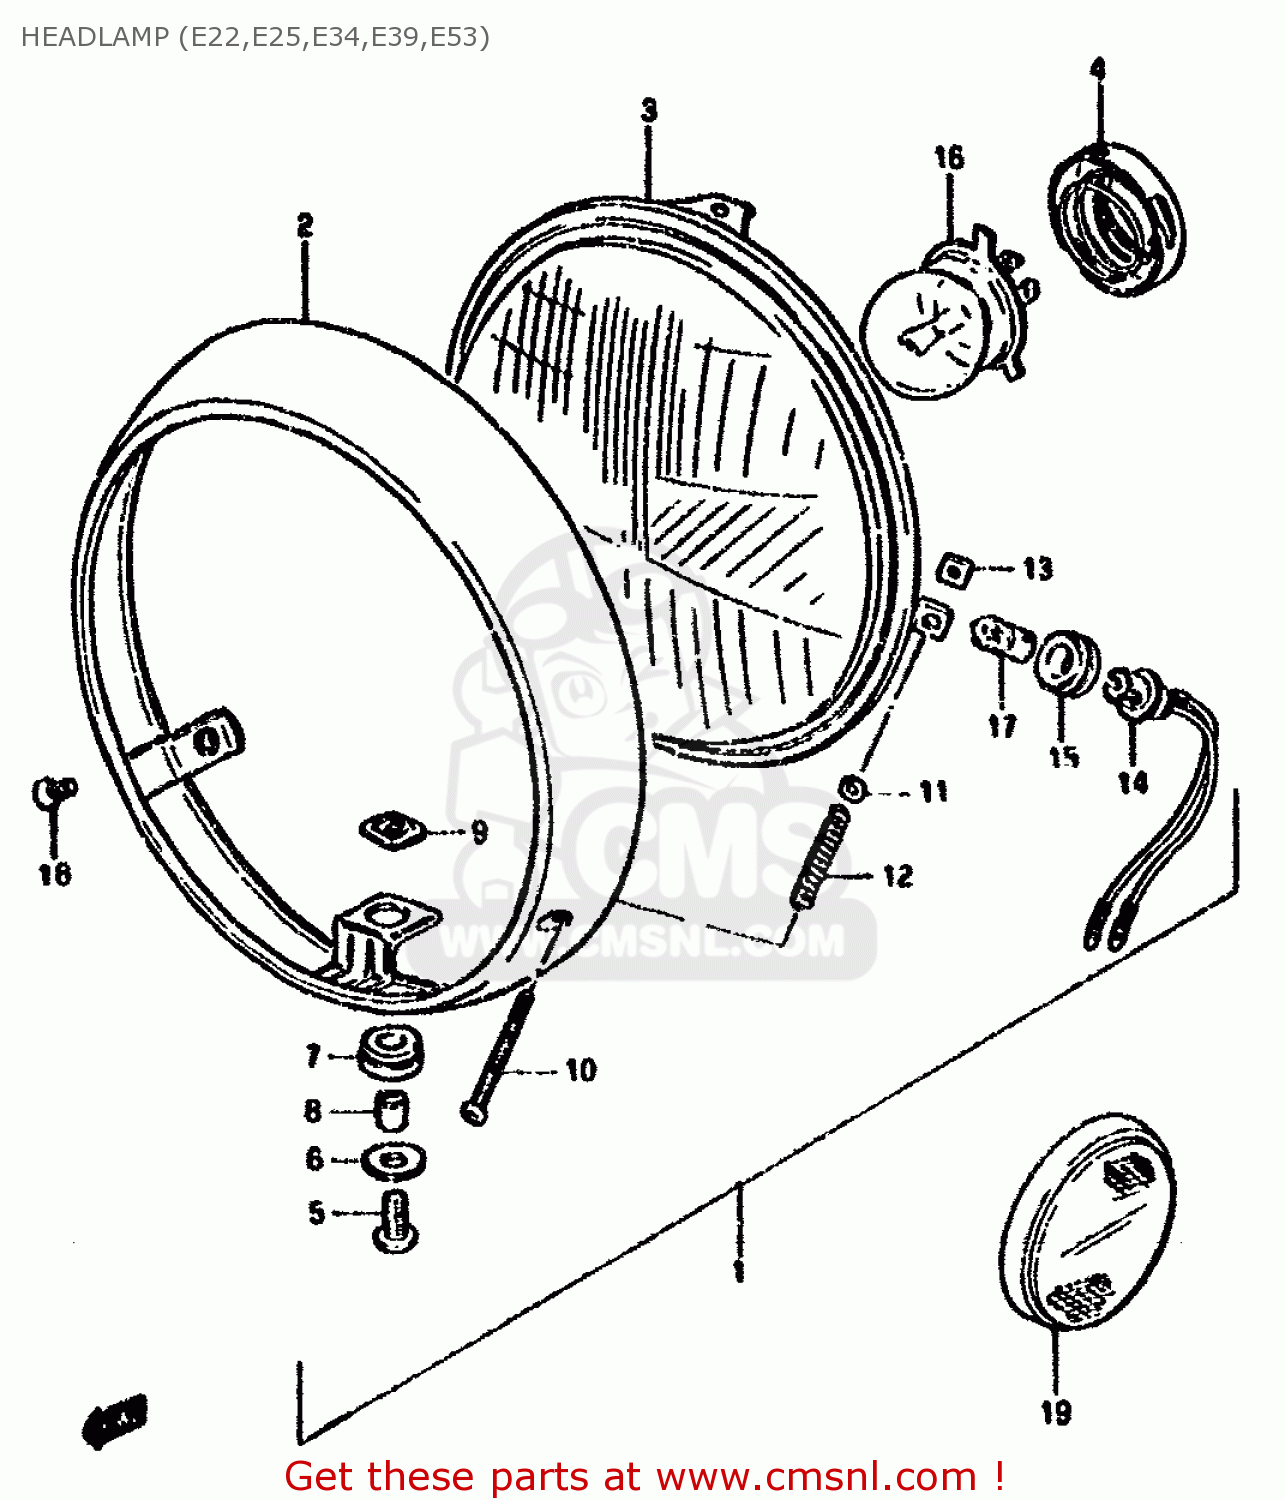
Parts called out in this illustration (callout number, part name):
1	HEADLAMP ASSY
2	RIM
3	LAMP UNIT
4	HOLDER,BULB
5	SCREW
6	WASHER
7	CUSHION
8	SPACER
9	NUT
10	SCREW HEAD LAM
11	WASHER
12	SPRING
13	NUT,HEADLAMP ADJUSTER
14	SOCKET
15	JOINT,RUBBER
16	BULB (12V, 45/40W)
17	BULB(12V4W)
18	SCREW
19	REFLEX REFLECTOR ASSY,FR SIDE
